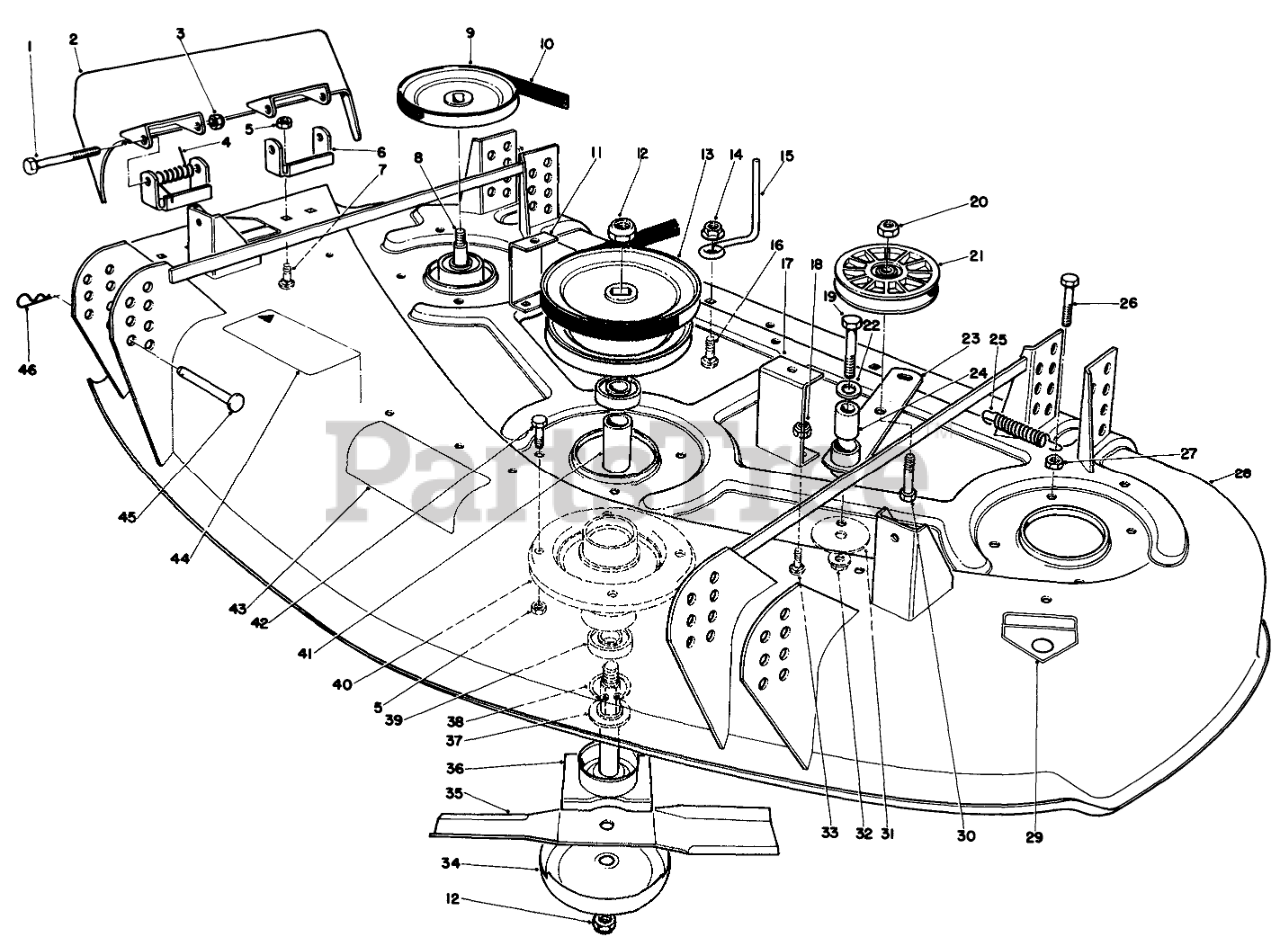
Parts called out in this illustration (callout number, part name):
1	SCREW-HH
2	GRASS DEFLECTOR WA R
3	NUT-HEX
4	SPRING
5	NUT-LOCK, CONE
6	Bracket-Pivot
7	SCREW-CARR
8	SPINDLE SHAFT WA
9	Pulley-Spindle
10	V-BELT
11	Bracket-Cover RH
13	PULLEY WA
14	NUT-HF
15	ROD-BELT
16	BOLT-CARR
17	Bracket-Cover
18	NUT-LOCK, NI
19	SCREW-HH
20	NUT-HEX
21	Pulley
22	WASHER-FLAT
23	Idler Arm
24	SLEEVE
25	Spring-Extension
26	SCREW-HH
27	NUT-JAM
28	Housing
29	DECAL-DANGER
30	SCREW-HH
31	WASHER-END
32	NUT-HF
33	BOLT-CARR
34	Cup
35	Blade
36	W.A.-SPINDLE SHAFT
37	SPACER-SPINDLE
38	RING-RETAINING
39	BEARING-BALL
40	Spindle Tube
41	BEARING SPACER
42	SCREW-HH
43	DECAL
44	CAUTION DECAL
45	PIN-CLEVIS
46	PIN-HAIR
